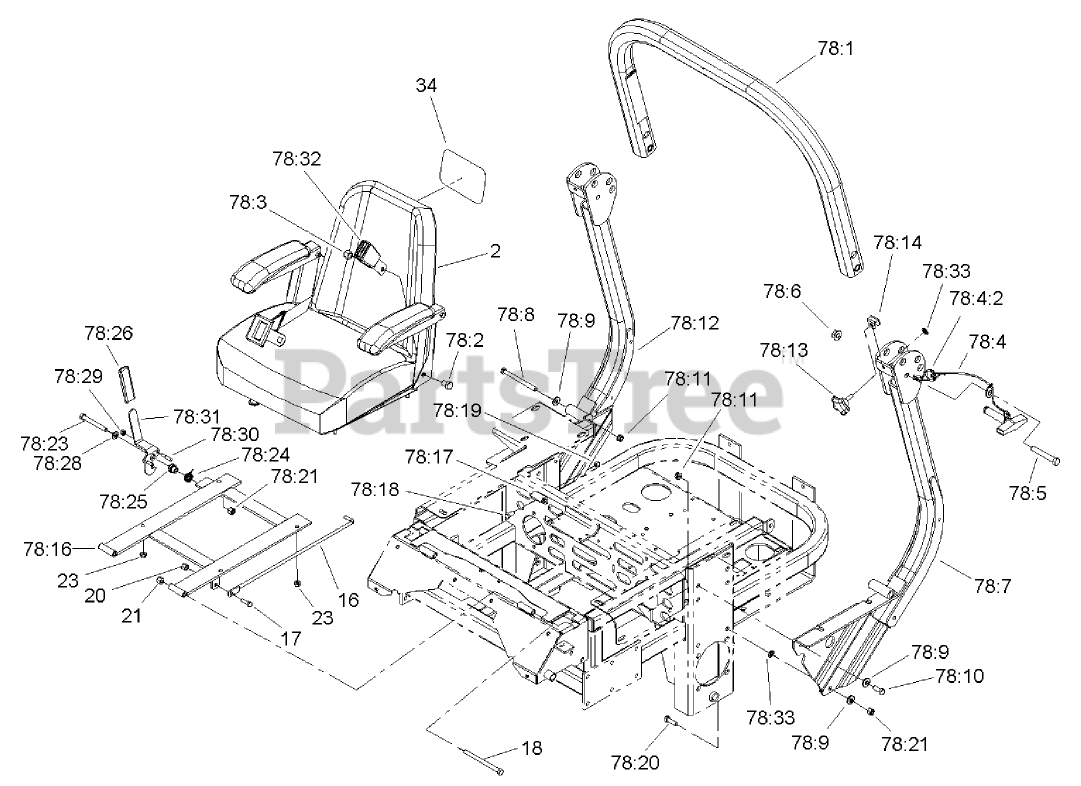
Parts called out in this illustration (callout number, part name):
2	SEAT ASM
16	ROD-HOLDUP, SEAT
17	SCREW-HH
18	SCREW-HH
20	NUT-LOCK, NI
21	NUT-LOCK, NI
23	NUT-HF
34	DECAL
78	ROPS ASM
78:1	Upper Tube ASM
78:2	SCREW-HH
78:3	NUT-LOCK
78:4	PIN LATCH ASM
78:4:2	Hairpin
78:5	SCREW-HH
78:6	NUT-HF
78:7	LH Rops ASM
78:8	SCREW-HH
78:9	WASHER-BELLEVILLE
78:10	SCREW-HH
78:11	NUT-HHF, WHIZ
78:12	RH Rops ASM
78:16	SEAT SUPPORT FRAME ASM
78:17	Catch-Latch, Seat
78:18	SCREW-HH
78:19	NUT-LOCK, NI
78:20	SCREW-HH
78:21	NUT-LOCK, NI
78:23	SCREW-HH
78:24	SPRING-TORSION
78:25	BUSHING-LATCH, SEAT
78:26	GRIP-HANDLE
78:28	WASHER-FLAT
78:29	NUT-LOCK, NI
78:32	Belt-Seat
78:33	NUT-PUSH
